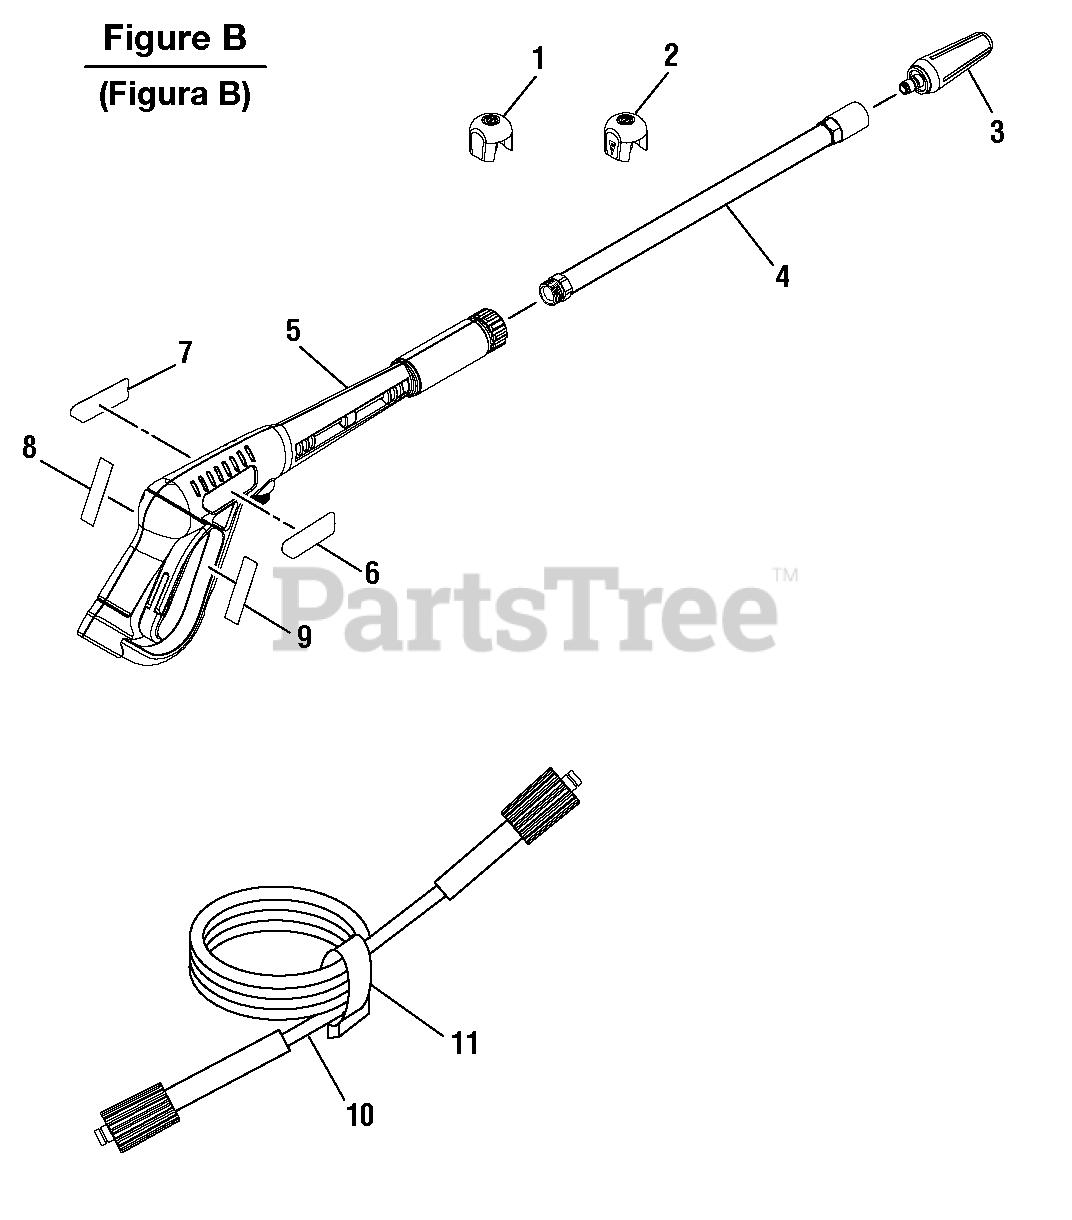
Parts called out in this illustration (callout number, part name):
1	Soap Nozzle
2	High Pressure Nozzle
3	Turbo Nozzle
4	Wand Assembly
5	Trigger Handle Assembly
6	Wand Logo Label
7	Wand Warning Label
8	Wand Rating Label
9	Wand Warning Label (French/Spanish)
10	Wand Hose
11	Hose Strap
